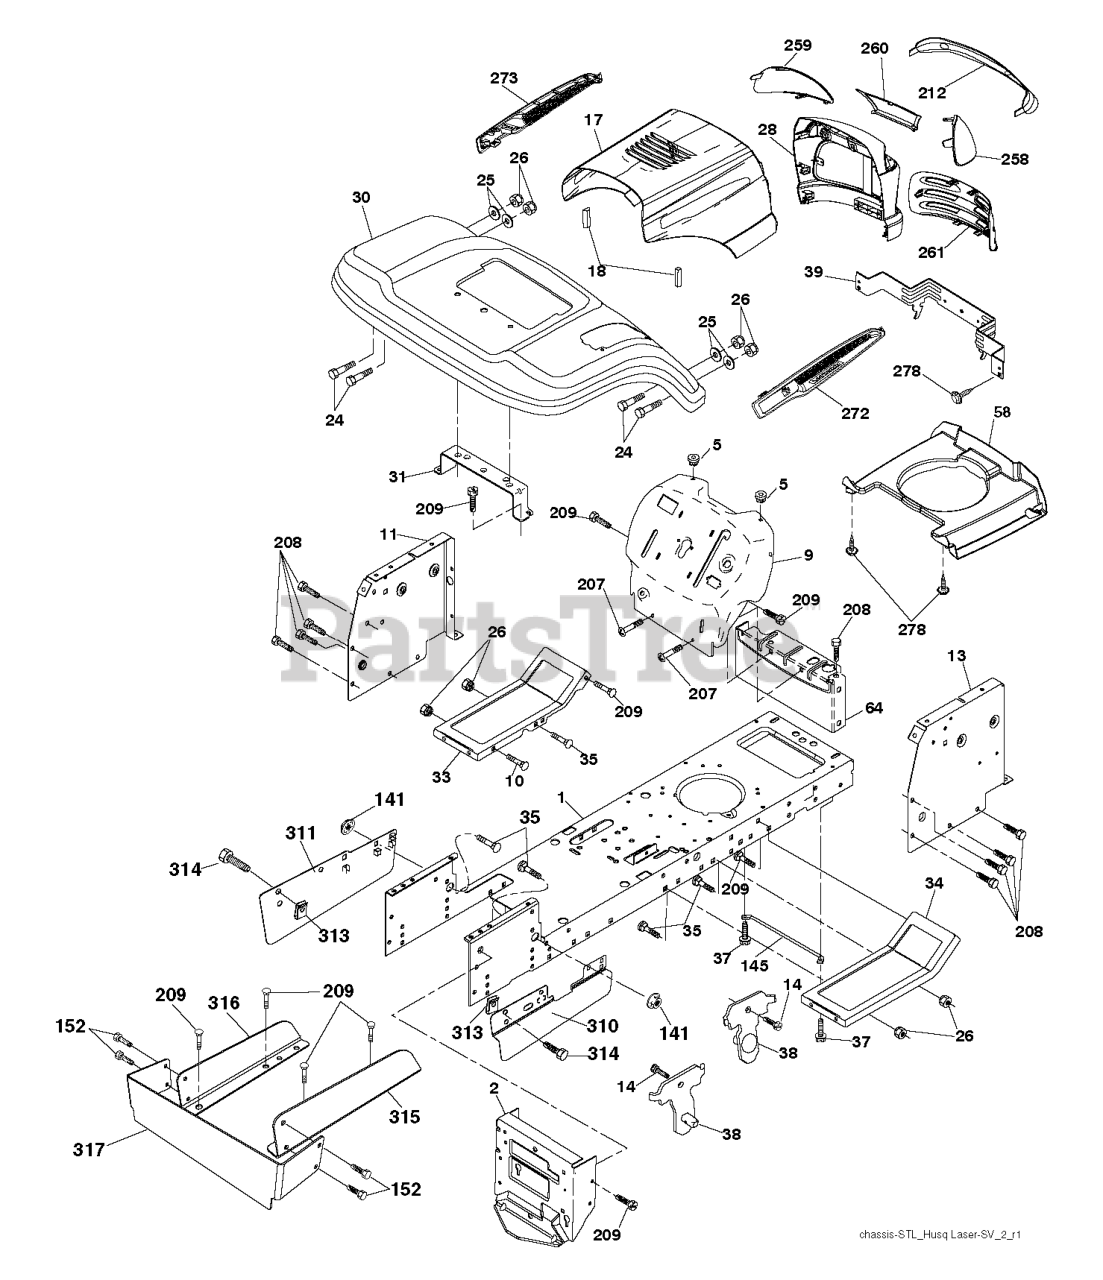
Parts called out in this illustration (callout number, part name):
1	CHASSIS STAMPING
2	DRAWBAR, 12GA
5	BUMPER.RUBBER.HOOD
9	DASH.SLKSCR.SL.PL.C.NA.NHMHUS
10	BOLT D
11	PANEL.DASH.LH.LTX
13	PANEL DASH RH
14	SCREW LT
17	VENT.HOOD.LASER.III
18	BUMPER.HOOD.LARGE.1.75"
24	BOLT
25	WASHER
26	NUT
30	FENDER.PNT.LTST.W/S.N/C.422ROS
31	BRACKET FENDER
33	FOOTREST.PNT.LH.BLACK
34	FOOTREST, RH
35	BOLT
37	Screw 5/16-18 x 1/2 Hex, Self Tapping 5/16-18 x 1/2
38	BRACKET.ASM.PIVOT.MOWER.REAR
39	BRACKET PIVOT
64	DASH LOWER
141	NUT LOCK FLG 3/8-16 UNC
145	ROD.PIVOT.HOOD
152	SCREW
207	SCREW, 5/16-18 X 1/2
208	SCREW 3/8-16X1/2
209	SCREW, 3/8-16X3/4
212	INSERT.LENS.REFLECTIVE
258	LENS LH
259	LENS LH
260	COVER.LENS.HUSQ.LASER
272	VENT.HOOD.LASER.
273	VENT.HOOD.LASER.
278	SCREW.#10 X 0.750.BOS
314	SCREW.1/4-20X5/8
